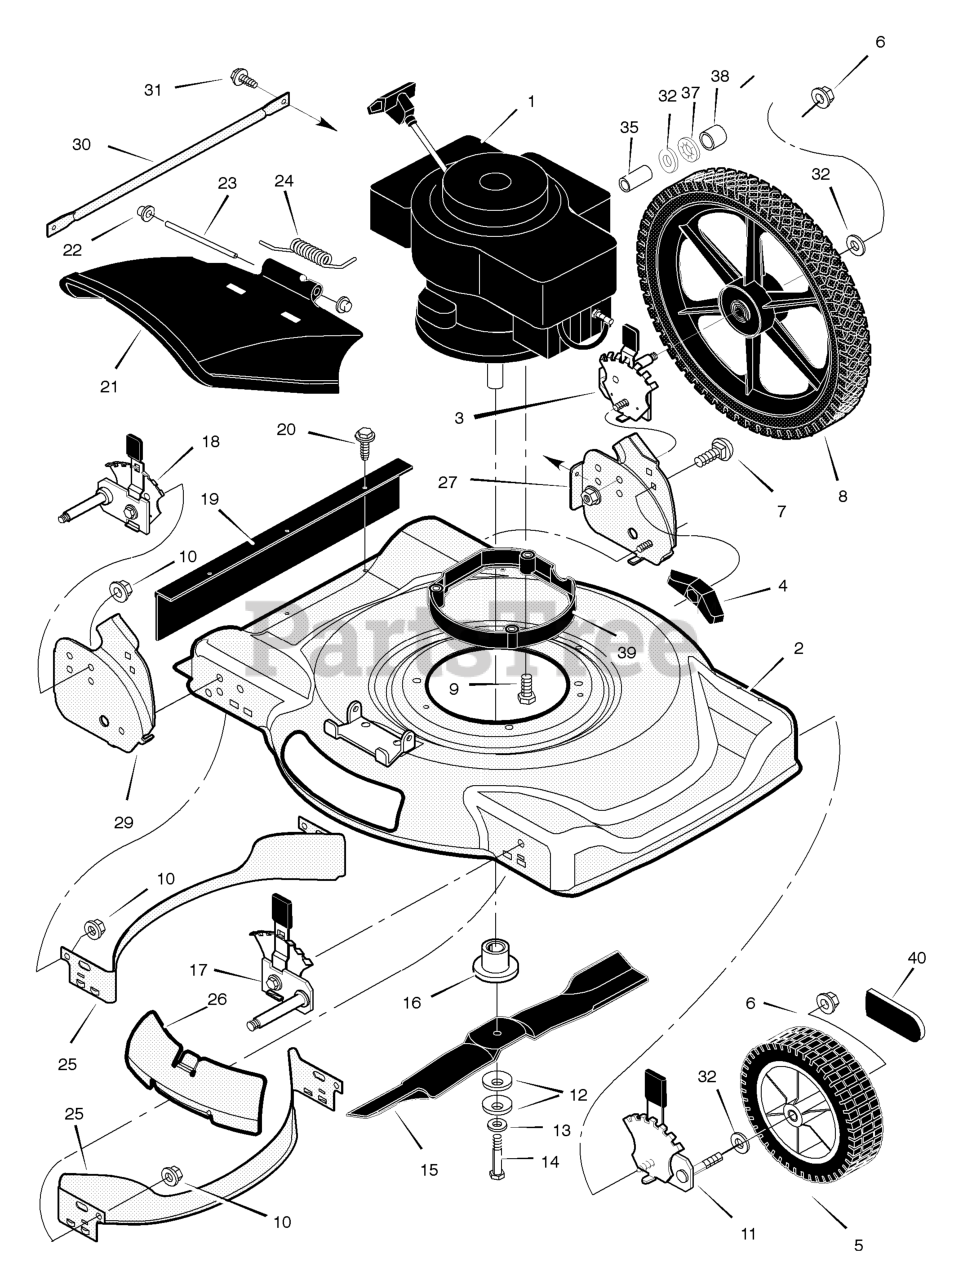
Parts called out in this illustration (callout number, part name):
2	Housing
3	Engine
3	Height Adjuster, Left Rear
5	Wheel and Tire, Front
6	Locknut, Flange
7	Bolt, Carriage
8	Wheel and Tire, Rear
9	Bolt, Engine
10	Nut
11	Height Adjuster, Left Front
12	Washer, Belleville
14	Bolt, Hex
15	Blade, Mulcher
16	Adapter, Blade
17	Height Adjuster, Right Front
18	Height Adjuster, Right Rear
19	Guard, Rear
21	Deflector, Chute
22	Push-On Cap
23	Pin, Pivot
26	Plate, Mulcher
27	Bracket, Left Handle
29	Bracket, Right Handle
34	Bolt
36	Washer
37	Nut, Speed
39	Base, Engine
40	Cap, Hub
